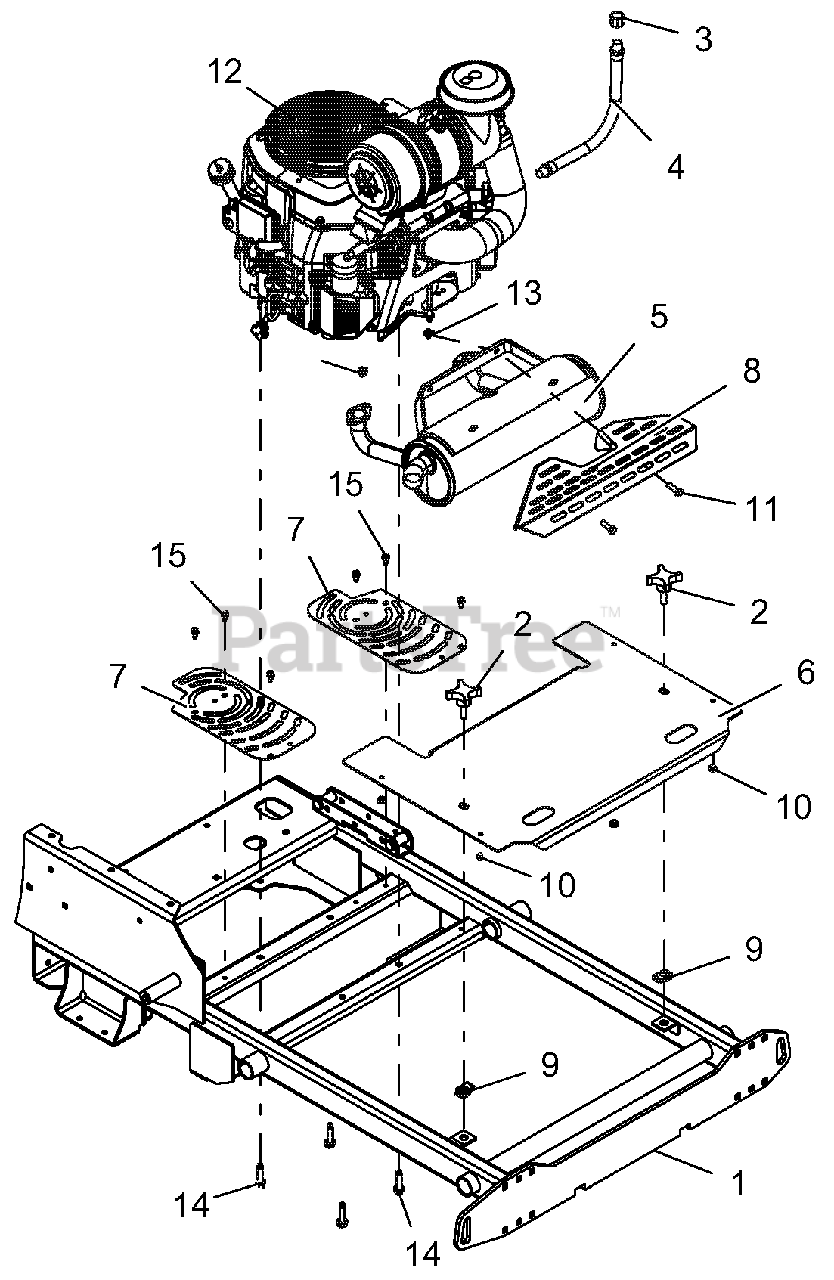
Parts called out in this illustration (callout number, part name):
1	WLDMT, FRAME PROSTANCE
2	KNOB, 3/8 X 1.25 - 4 PRONG
3	PIPE, CAP 3/8 NPT FEMALE
4	HOSE, HYD .38-11-OK M6N0-M6N0
5	MFLR, KOHLER
6	SHIELD, FRONT PRO-STANCE-RED
7	GUARD, FAN
8	GUARD, HEAT SHIELD (BLACK)
9	NUT, RTNR .375-16X.37
10	BUMPER GROMMET .125 X .25 REV
11	BLT-HEX .31-18X1.00 GR5 YWZC
12	ENGINE, KOHLER EFI ECV740
13	NUT-LK-NYL-FLG .31-18 YWZC
14	SCR-TAP .38-16X1.50 HWH TR YZ
15	SCR-TAP .25-20X.50 HWH TR YWZ
